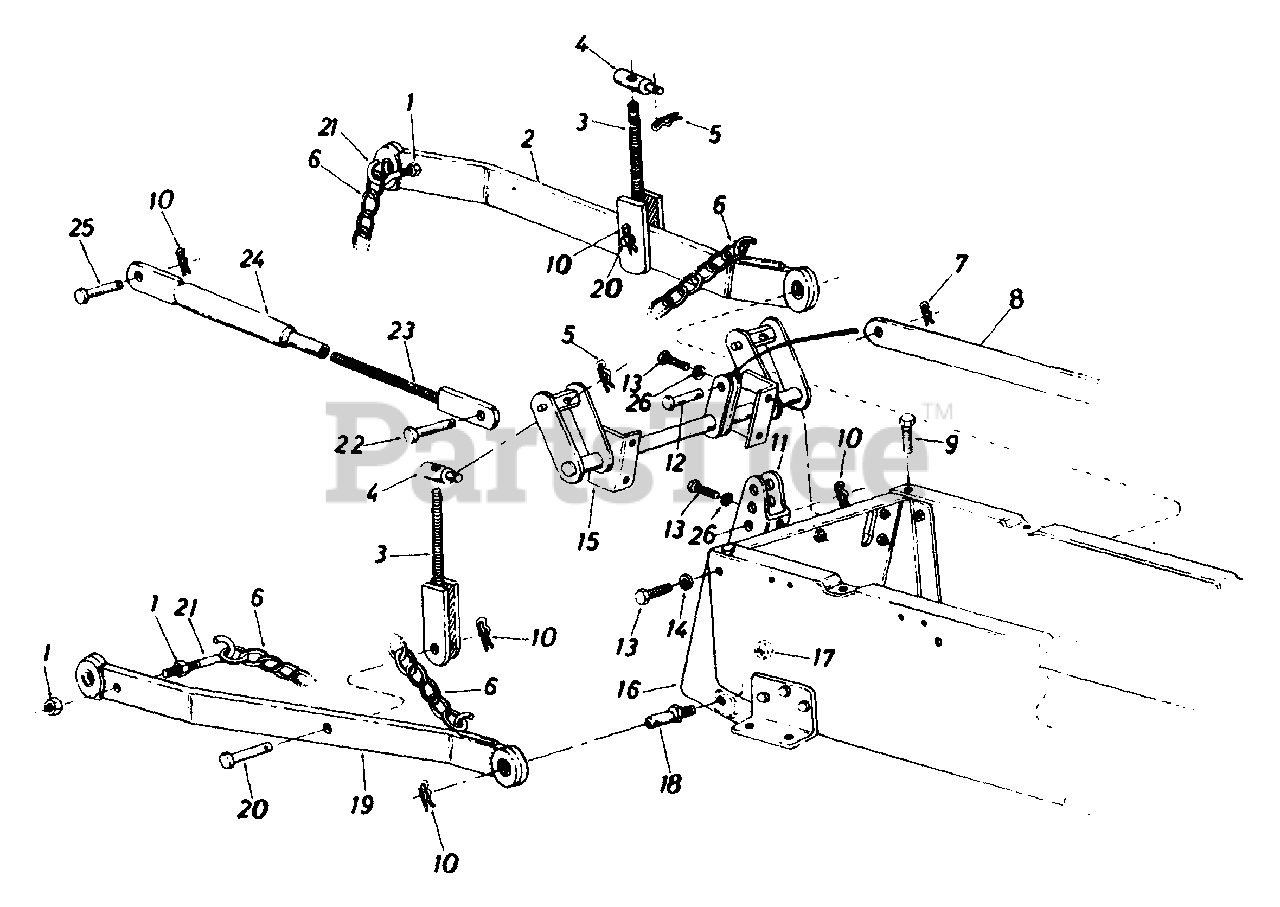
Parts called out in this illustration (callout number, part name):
1	Hex Cent. L-Nut 7/16-14 Thd.
4	Clevis Pin
5	Hitch Pin Clip
6	Chain - 20 Links
7	Cotter Pin 1/8" Dia. x 1.25" Lg.
8	Push Bar Ass'y.
9	Hex Scr. 3/8-16 x .75" Lg.
10	Hairpin Cotter
11	Hitch Brkt.
12	Clevis Pin
13	Hex Scr. 3/8-16 x .75" Lg.
14	L-Wash. 3/8" Scr. - H.D.
15	Rear Lift Shaft Ass'y.
16	Hitch Plate Ass'y.
17	Hex Cent. L-Nut 5/8-18 Thd.
18	Link Clevis Pin
19	Draft Bar Ass'y. - R.H.
20	Clevis Pin .63" Dia. x 1.66" Lg.
21	Hitch Chain Hook
22	Clevis Pin .63" Dia. x 2.4" Lg.
23	Clevis Screw
24	Clevis Tubing
25	Clevis Pin .63" Dia. x 2.4" Lg.
26	L-Wash. 3/8" Scr. - H.D.
